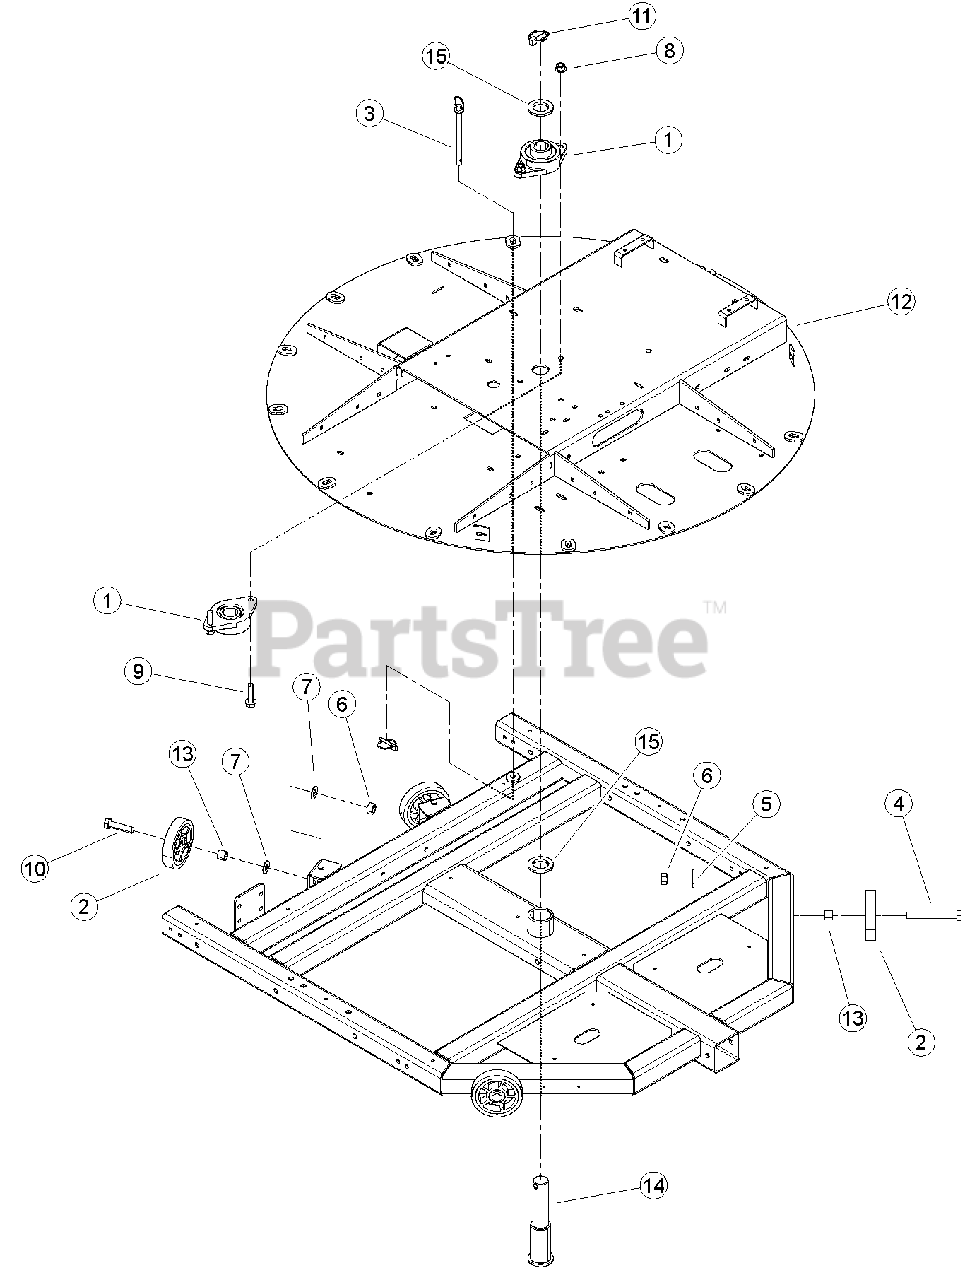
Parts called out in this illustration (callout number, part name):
1	BEARING, 1-1/2" 2-BOLT SET SCREW
2	ROLLER, 5 X 1 X 5/8 NOFF AL
3	PIN, HITCH 1/2 X 6-1/2 W/ LYNCH
4	BOLT, 5/8 X 5 HEX HD G5 ZP
5	WASHER, 5/8" FLAT ZP
6	NUT, 5/8" CENTERLOCK ZP GR5
7	WASHER, 5/8" SAE FLAT ZP
8	NUT, 1/2-13 NYLOCK FLANGE
9	BOLT, 1/2-13 X 2 HWH GR5 CZP
10	BOLT, 5/8 X 2-1/2 HEX HD GR5 ZP
11	PIN, 7/16 X 1-3/4 LYNCH
12	WELDMENT, CHIPPER BASE
13	SPACER, 7/8 X 3/4
14	PIN, CHIPPER PIVOT
15	SPACER, 2.00 X 1.50 X 0.25
